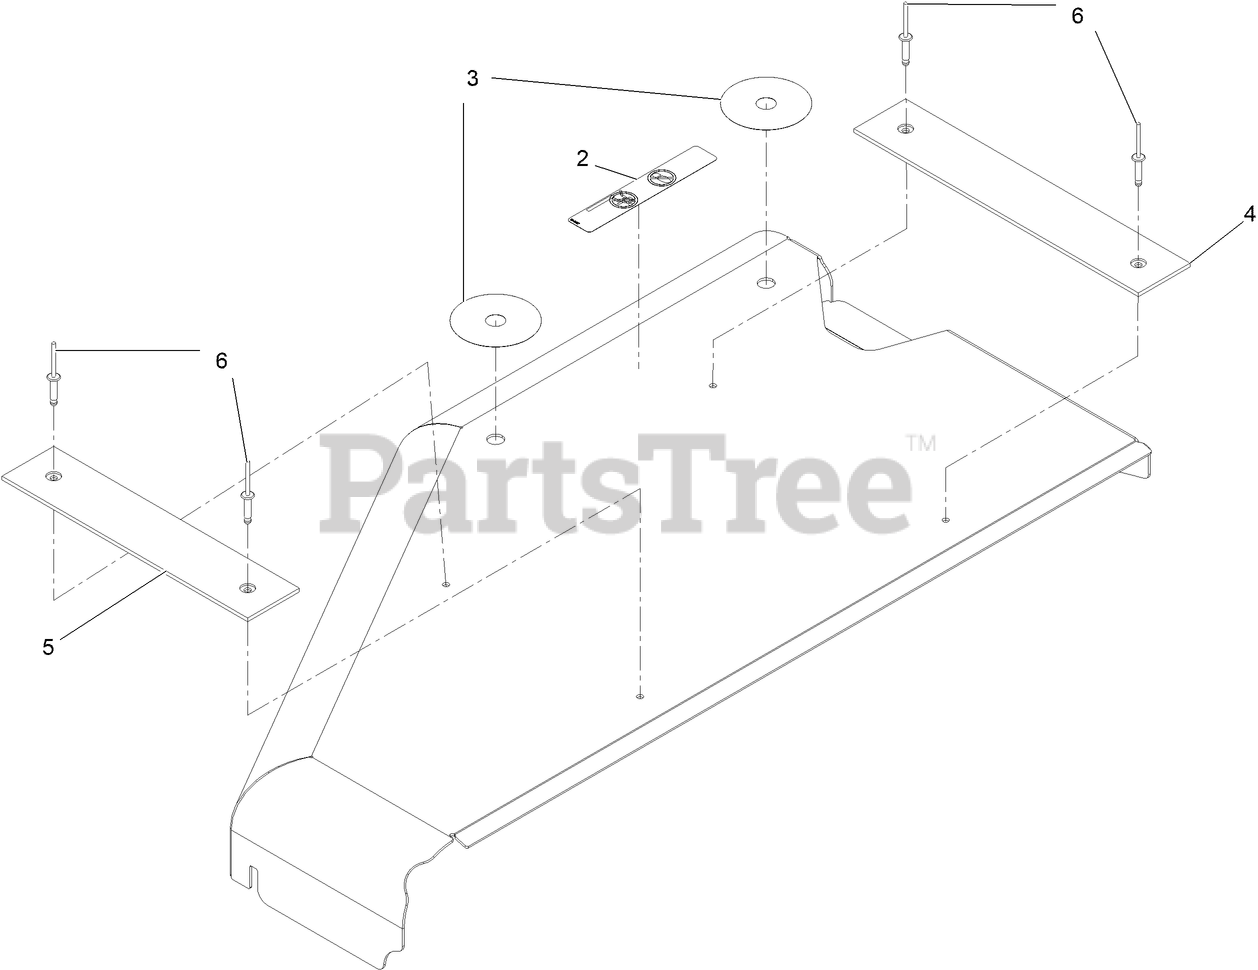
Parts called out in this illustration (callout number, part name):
2	DECAL-NO STEP
3	DECAL-SCRATCH COVER
4	Plate-Uhmw 2"
5	PLATE-FRONT
6	Rivet-Pop
